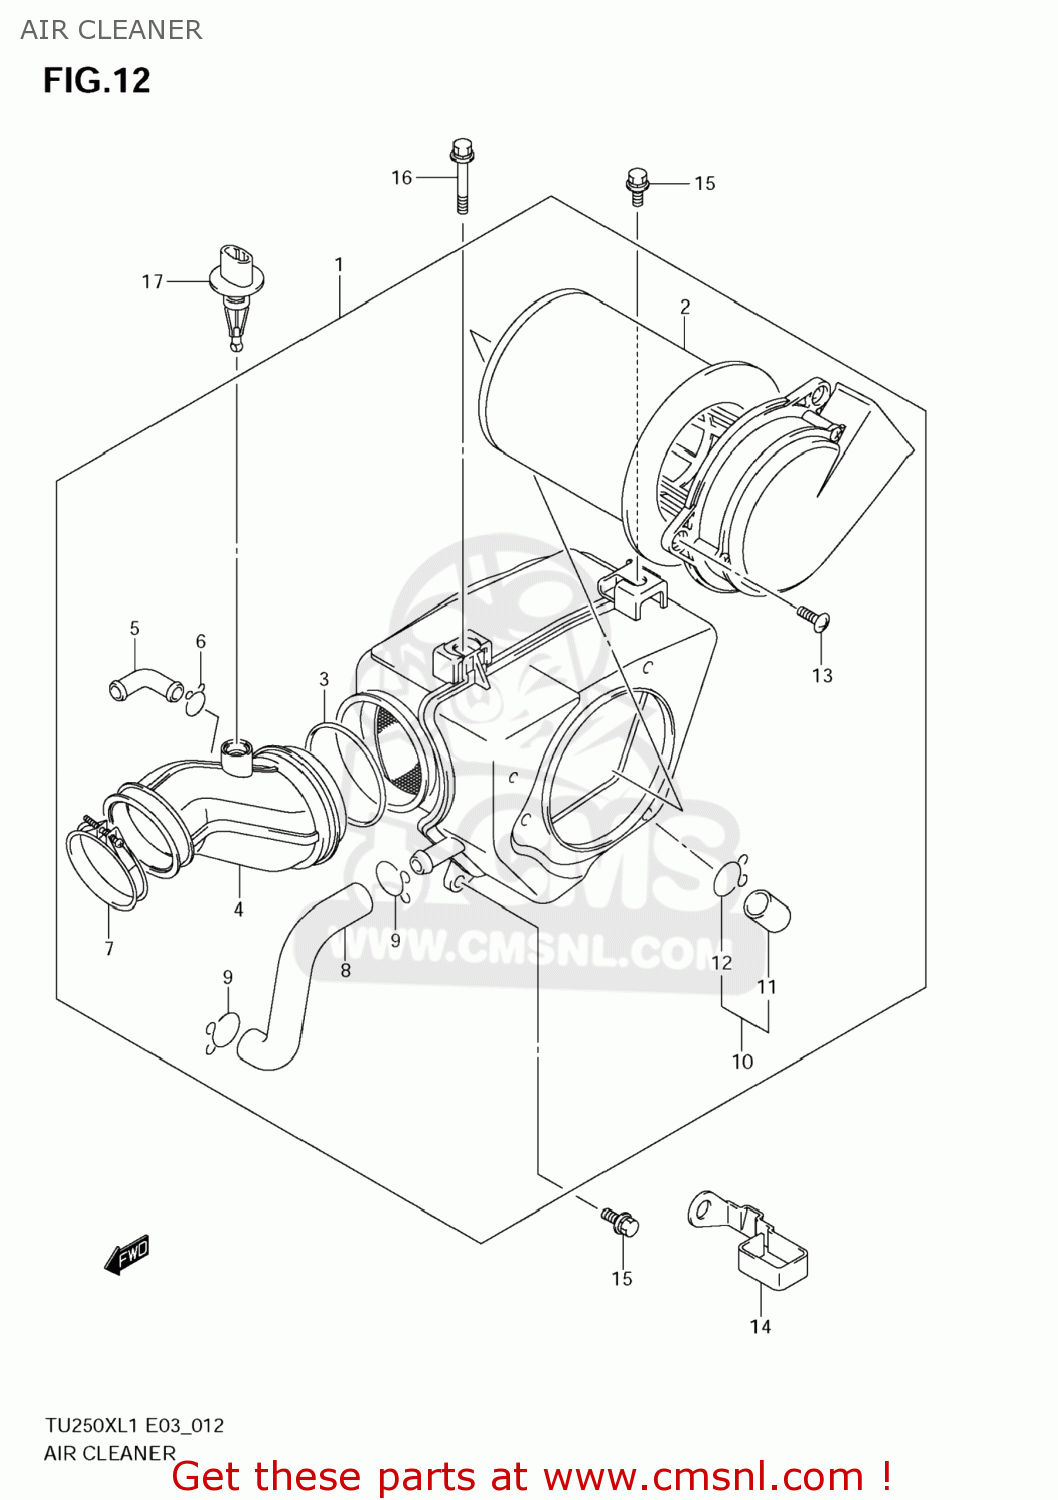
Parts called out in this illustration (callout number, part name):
1	CLEANER ASSY,AIR
2	FILTER
3	CLAMP,AIR CLEANER SIDE
4	TUBE,OUTLET
5	JOINT
6	CLIP
7	CLAMP
8	TUBE,BREATHER
9	CLIP
10	PLUG ASSY,DRAIN
11	PLUG
12	CLIP
13	SCREW
14	CLAMP,AIR CLEANER DRAIN TUBE
15	BOLT
16	BOLT
17	SENSOR,INLET AIR TEMP
